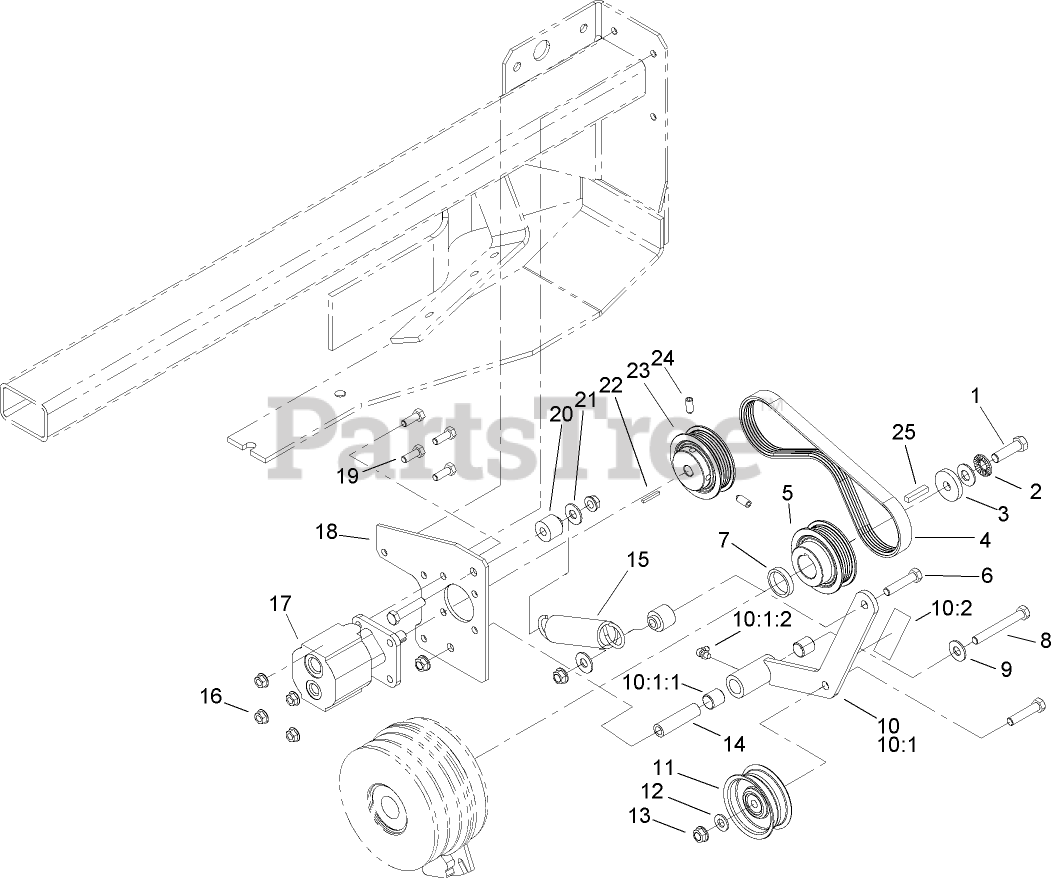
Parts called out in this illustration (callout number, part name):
1	SCREW-HH
2	WASHER-SPRING
3	WASHER-CLUTCH
4	BELT-POLY V
5	SHEAVE-5 RIB
6	SCREW-HH
7	SPACER-PUMP DRIVE, FAN
8	SCREW-HH
9	WASHER-FLAT
10	WHEEL PUMP TENSION ASM
10:1	TENSIONER ASM
10:1:1	SLEEVE-BEARING
10:1:2	FITTING-GREASE, 90 DEG
10:2	DECAL-WARNING
11	SHEAVE-IDLER
12	WASHER-FLAT
13	NUT-HHF, WHIZ
14	BUSHING-PIVOT, IDLER
15	SPRING-EXTENSION
16	NUT-HF
17	PUMP-FAN, HYD
18	PLATE-MATING, FAN PUMP
19	SCREW-HH
20	SPACER-SPRING, FAN PUMP
21	WASHER-FLAT
22	KEY-SQUARE
23	SHEAVE-5 RIB
24	SCREW-SET, HSH
25	KEY-SQUARE
